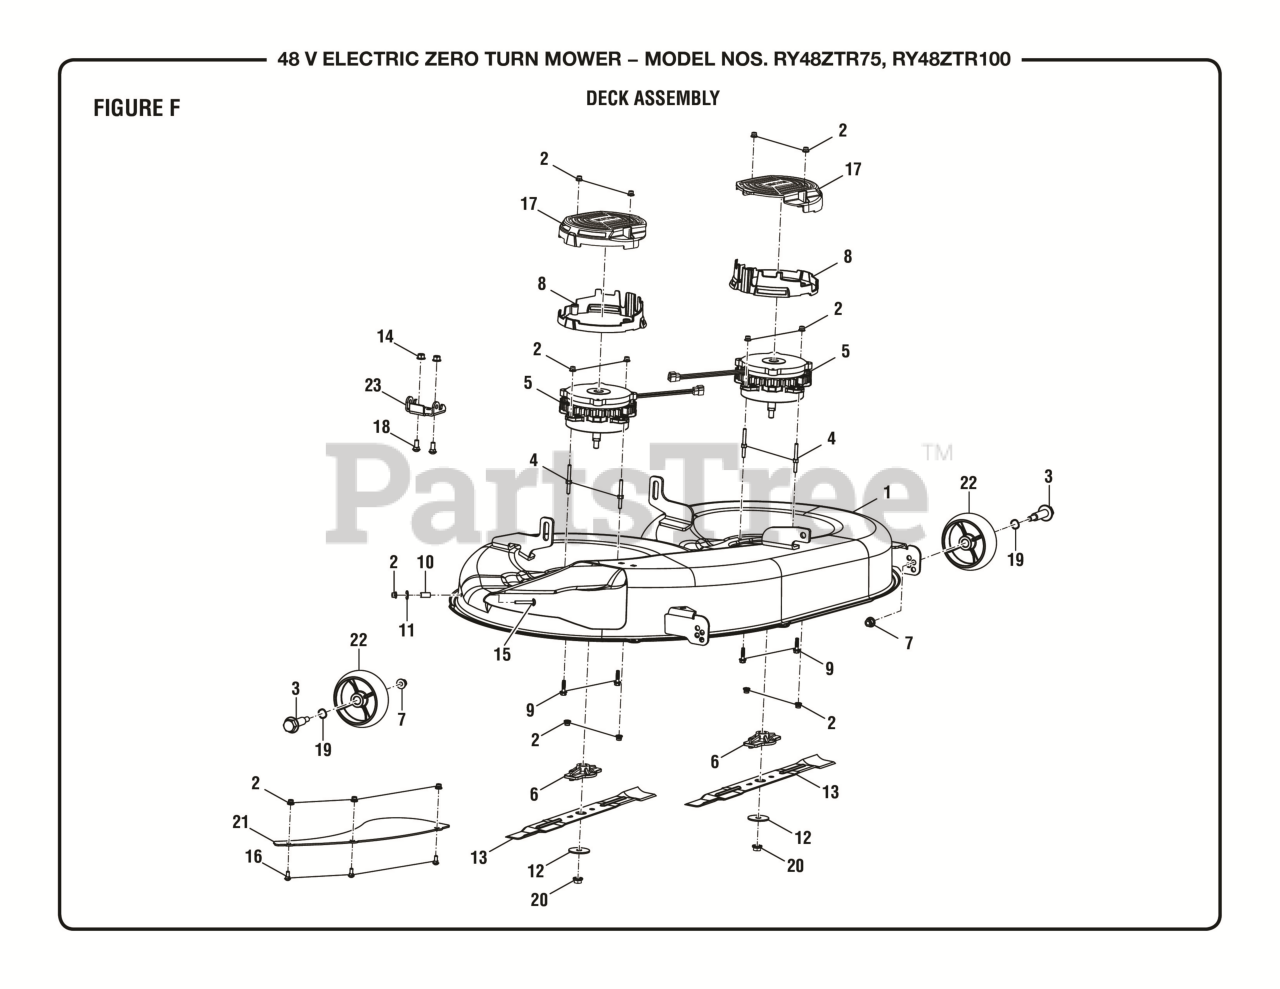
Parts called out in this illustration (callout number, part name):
1	Deck, 42 in
2	Flange Lock Nut (M6 x 1.00)
3	Shoulder Bolt (M10 x 70 mm)
4	Threaded Stud (M6 x 35 mm)
5	Deck Motor
6	Blade Adapter
7	Lock Nut (M10 x 1.5 mm)
8	Deck Motor Cover, Bottom
9	Flange Bolt (M6 x 25 mm, Hex Hd.)
10	Deck Bagger Chute Mounting Shaft
11	Washer (OD18 x ID6.4 x 1.6t)
12	Blade Retainer Washer
13	21 in. Blade
14	Flange Nut (M8) (For Drive Motor Controller V)
15	Screw (M6 x 40, Soc Hd.)
16	Carriage Bolt (M6 x 16 mm)
17	Deck Motor Cover, Top
18	Carriage Bolt (M8 x 20 mm)
19	Spring Washer (OD20.5 x ID17 x 0.3t)
20	Flange Lock Nut (M10 x 1.25)
21	Deck Baffle (42 in.)
22	Front Deck Roller Wheel (124.5 Dia.)
23	Discharge Chute Mounting Bracket
